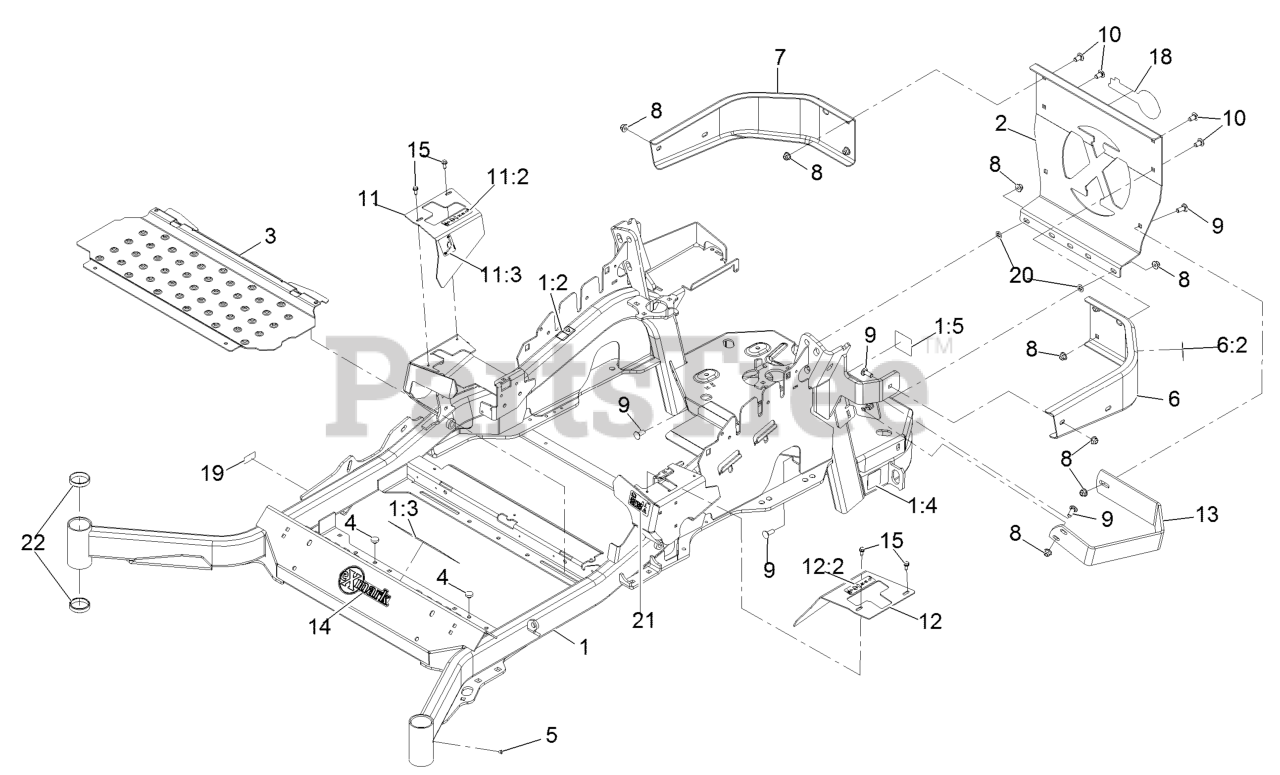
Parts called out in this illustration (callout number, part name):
1:2	DECAL-WARNING
1:3	DECAL-DANGER
1:4	DECAL-HAZARD, PINCHED FINGER
1:5	DECAL-SPARK ARRESTER
2	PLATE,REAR GUARD
6	LH BUMPER ASM
6:2	DECAL-WARNING
7	BUMPER-RH
8	NUT-HF, NI
9	SCREW-CARR
10	SCREW-CARR
11	RH MOTION CONTROL COVER ASM
11:2	DECAL-CONTROL, MOTION
11:3	DECAL-PARK BRAKE, CE
12	LH MOTION CONTROL COVER ASM
12:2	DECAL-CONTROL, MOTION
13	GUARD-MUFFLER
14	DECAL-EXMARK LOGO
15	SCREW-HWH
18	DECAL-EXMARK LOGO
19	Decal-Patent Ttco.Com
20	NUT-PUSH
21	DECAL-FUEL FILL, CE
22	CUP-BEARING
